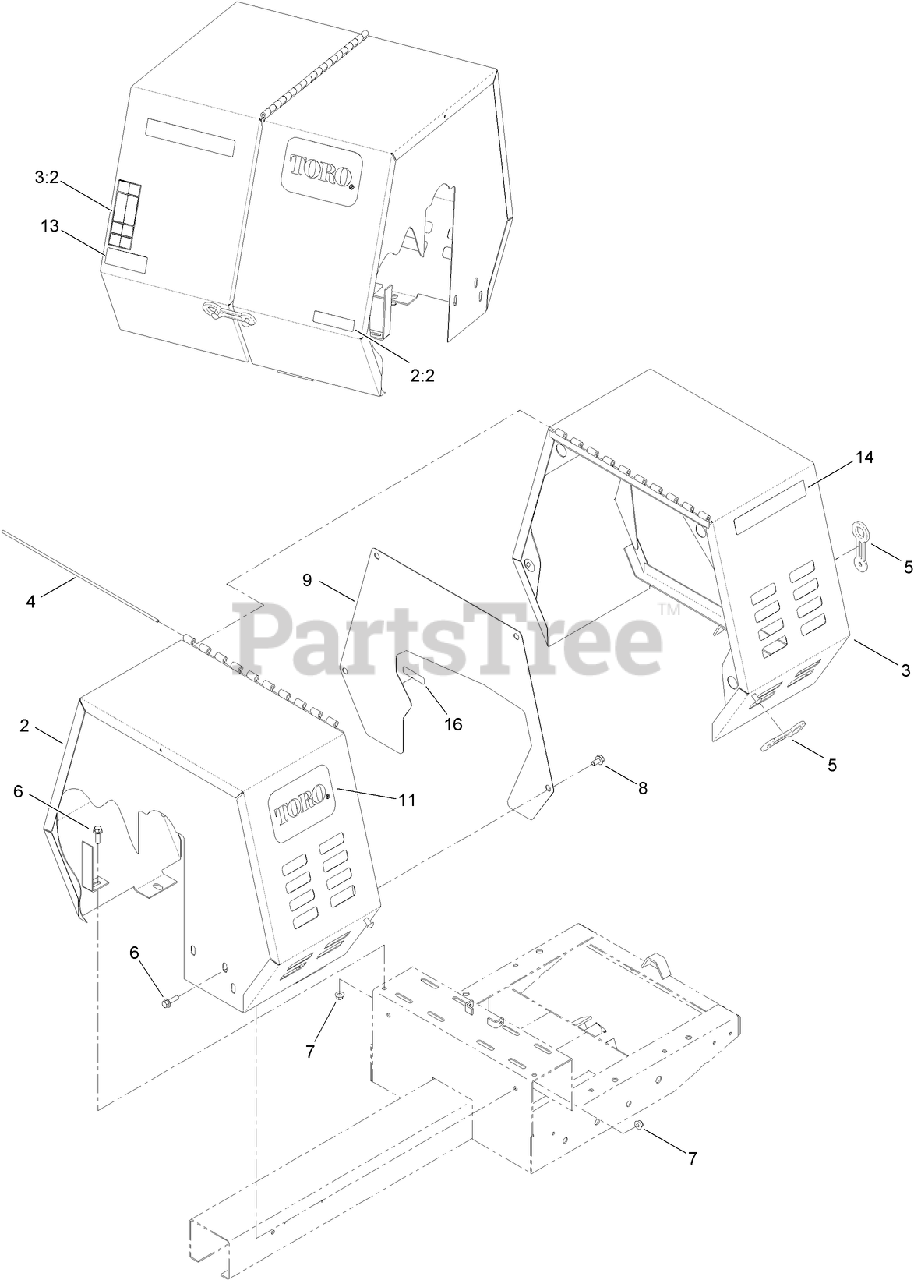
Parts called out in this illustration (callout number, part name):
2	STATIONARY COWL ASM
2:2	DECAL-ARRESTER, SPARK
3	MOVABLE COWL ASM
3:2	DECAL-WARNING
5	LATCH-RUBBER
6	SCREW-HHF
7	NUT-HF, NI
8	SCREW-HWH
9	PLATE-GUARD, BELT
11	DECAL
14	DECAL-MM-650E
16	DECAL-GREASE
